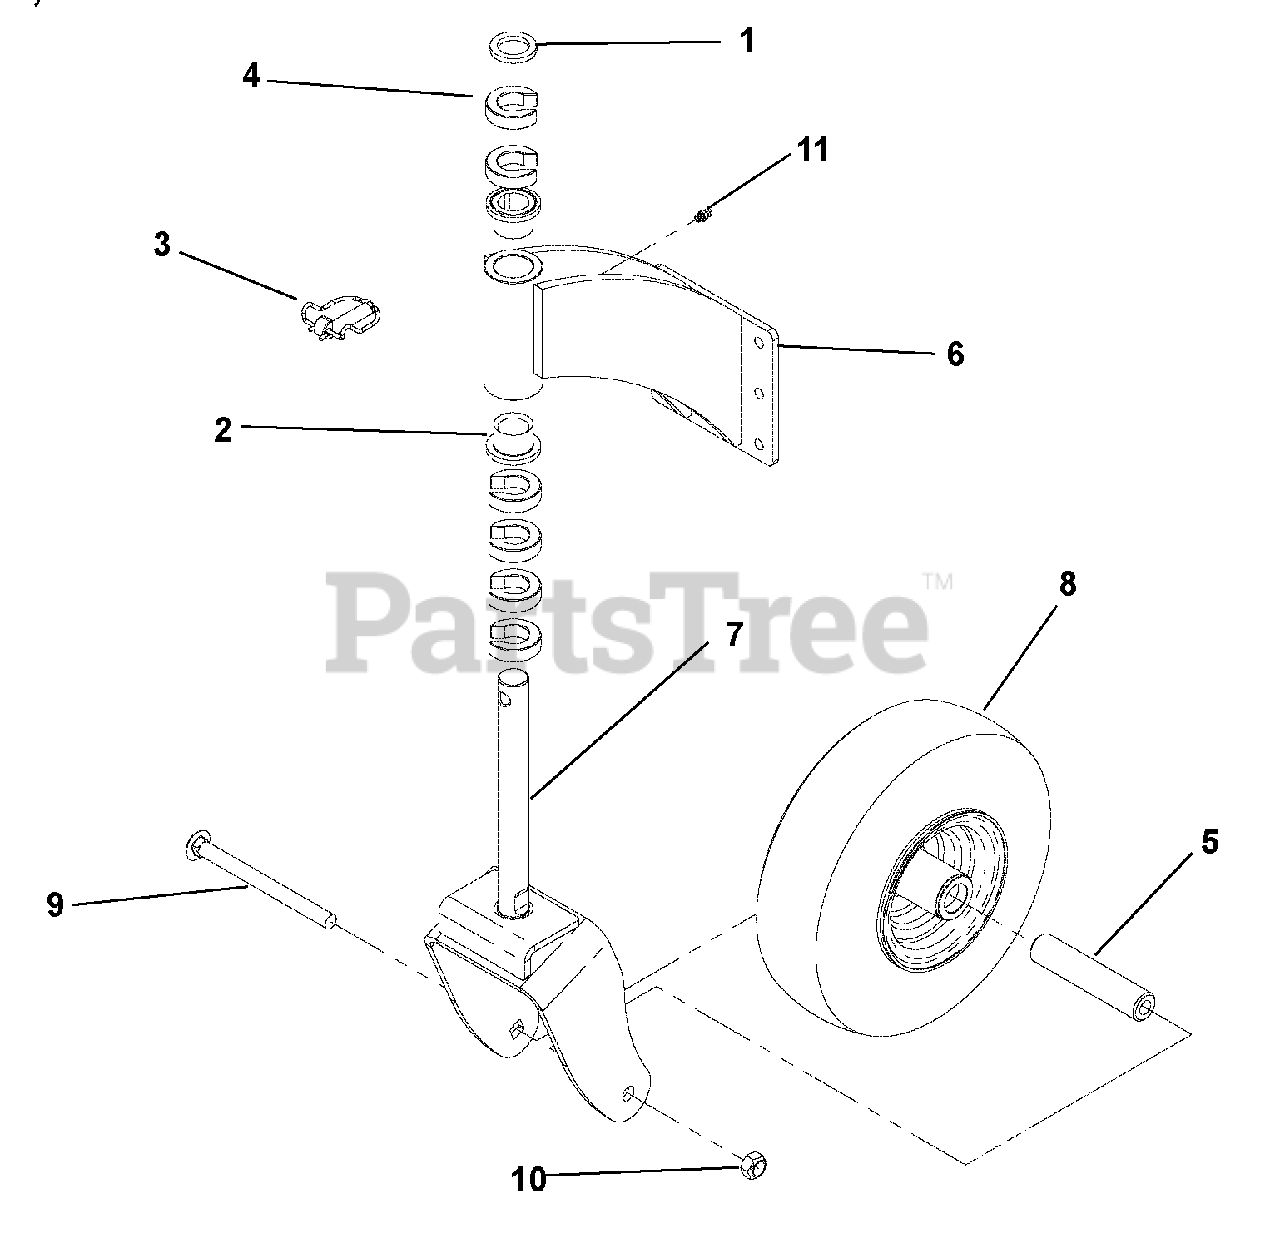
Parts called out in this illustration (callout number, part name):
1	Bushing, 1.03 x 1.50 x .179
2	Bearing, FLG 1.00 x 1.25 x 1.00
3	Pin, Lock .438 x 2.00
4	C-Spacer, 1.00 x 1.77 x .50
5	Tube, 1.00 x .50 x 4.76
6	Weldment, Caster Mount Bracket
7	Weldment, Front Wheel Fork
8	Wheel, Front 11 x 4 x 5
9	Bolt, 1/2-13 x 6.00 CRG
10	Locknut, 1/2-13 Crown
11	Grease Zerk, 1/4-28 STR .69 LG
